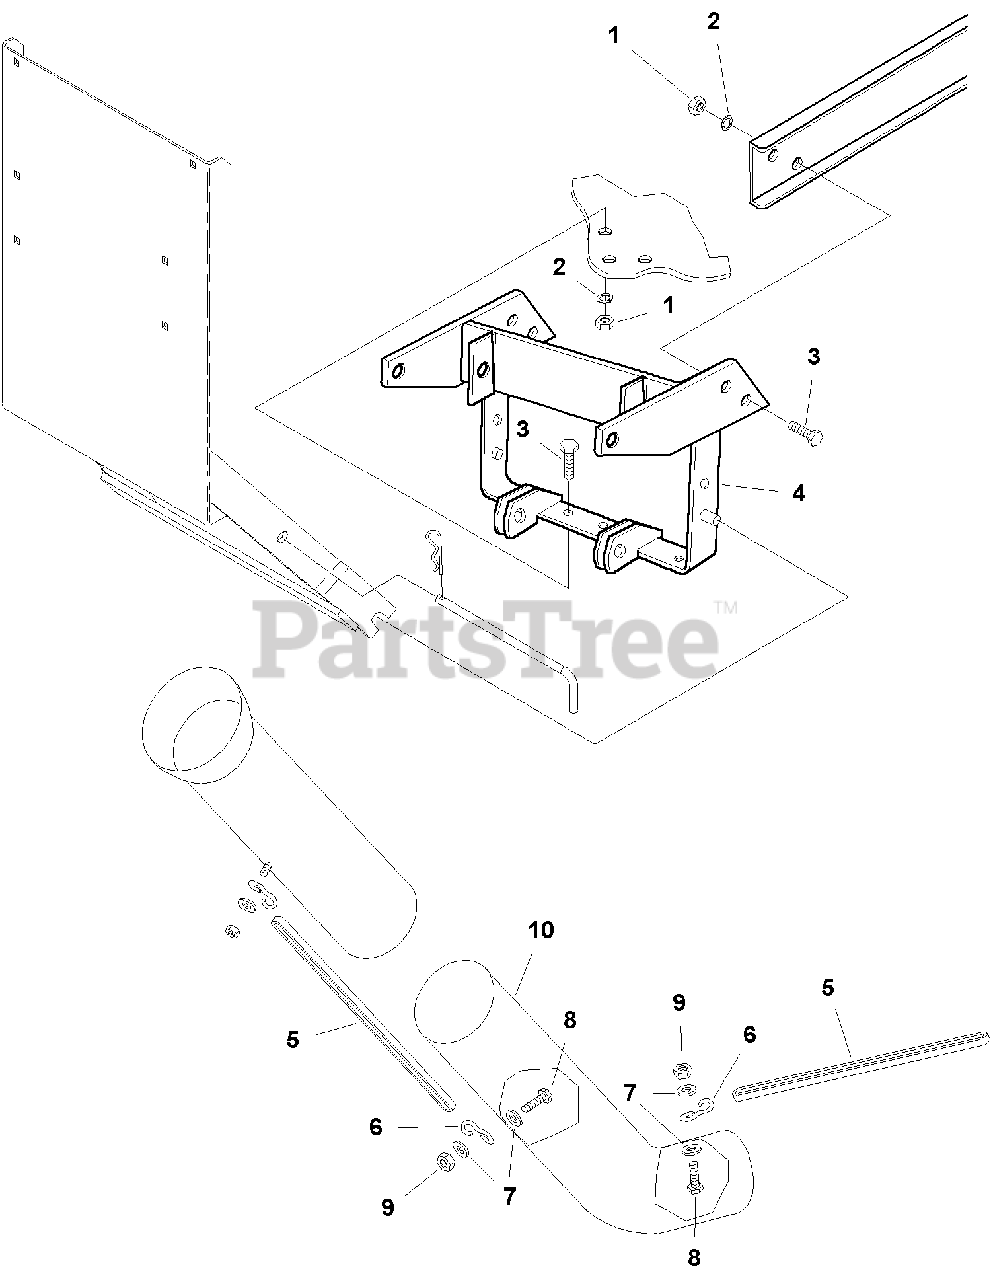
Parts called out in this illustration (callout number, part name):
1	NUT,Hex, 1/2-13
2	LOCKWASHER, 1/2
3	CAPSCREW, Hex, Head, 1/2-13 x 1-1/4
4	HITCH ASSEMBLY, Grass Catcher
7	WASHER, 1/4
8	CAPSCREW, Hex Head, 1/4-20 x 1-1/4
9	LOCKNUT, Hex, 1/4-20
10	CHUTE, Lower
